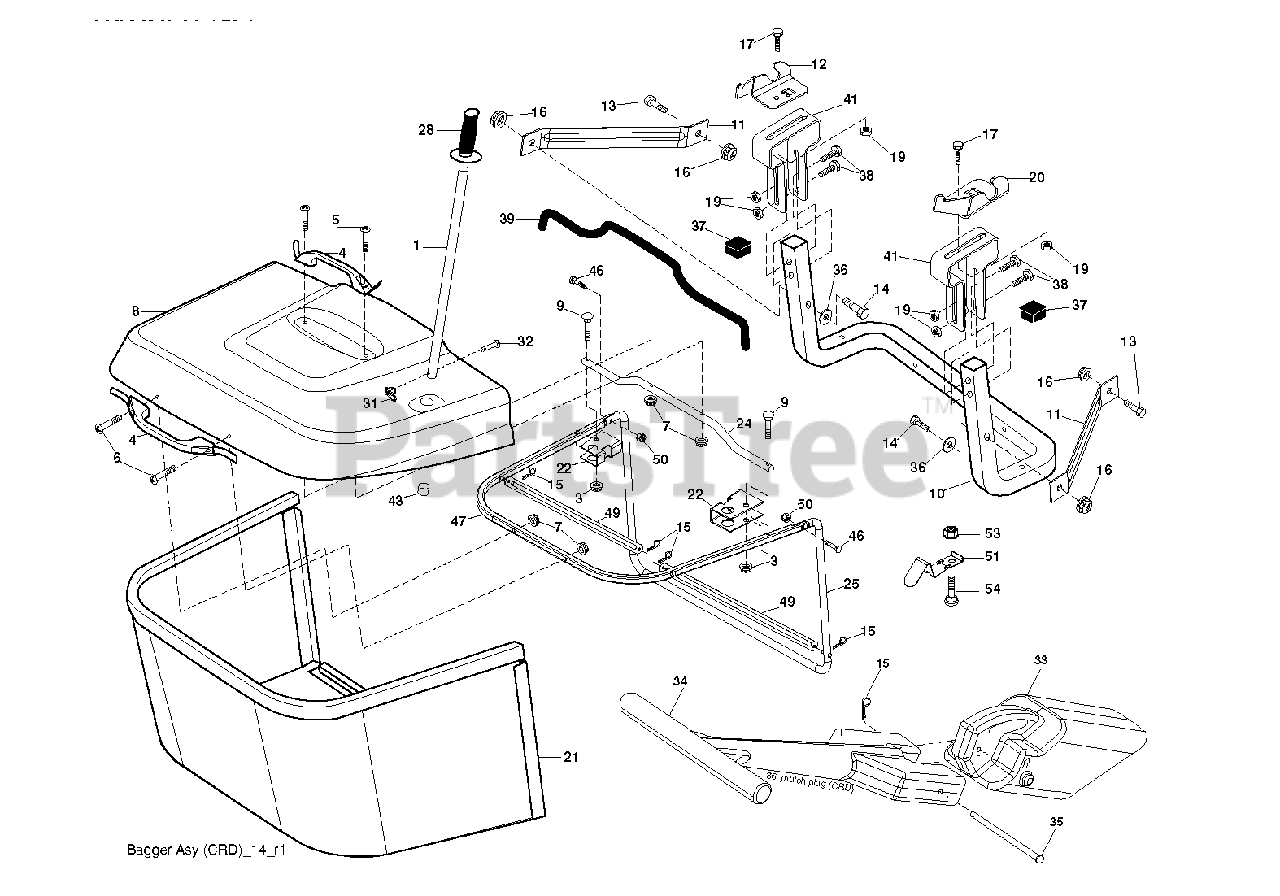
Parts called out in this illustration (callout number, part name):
1	TUBE.PNT.HDL.BAGGER.
3	NUT T
5	SCREW.PAN.HEAD
11	BRACKET
14	BOLT-HEX EAK
15	RETAINER-SPRNG RB
16	NUT LOCK FLG 3/8-16 UNC
17	BOLT
19	NUT LOCK HEX FLANGE 5/16-18
20	BRKT.PIVOT.RH.CRD
21	BAGGER.ASM.CRD.2007
22	BRACKET
24	TUBE
28	GRIP.HANDLE.BLACK
31	RETAINER CLIP
32	RIVET,DRILLED
33	MULCHING.PLUG.1078.CRD.NON-TEX
35	PIN
38	BOLT.5/16-18X2.5
39	SEAL.BAGGER.CRD
41	BRACKET.BAGGER.SD.
43	PLUG, TUBING END
46	BOLT.CARRIAGE.5/16-18
50	NUT.71038.31-18.HEX.NYLOCK
53	NUT
54	BOLT
